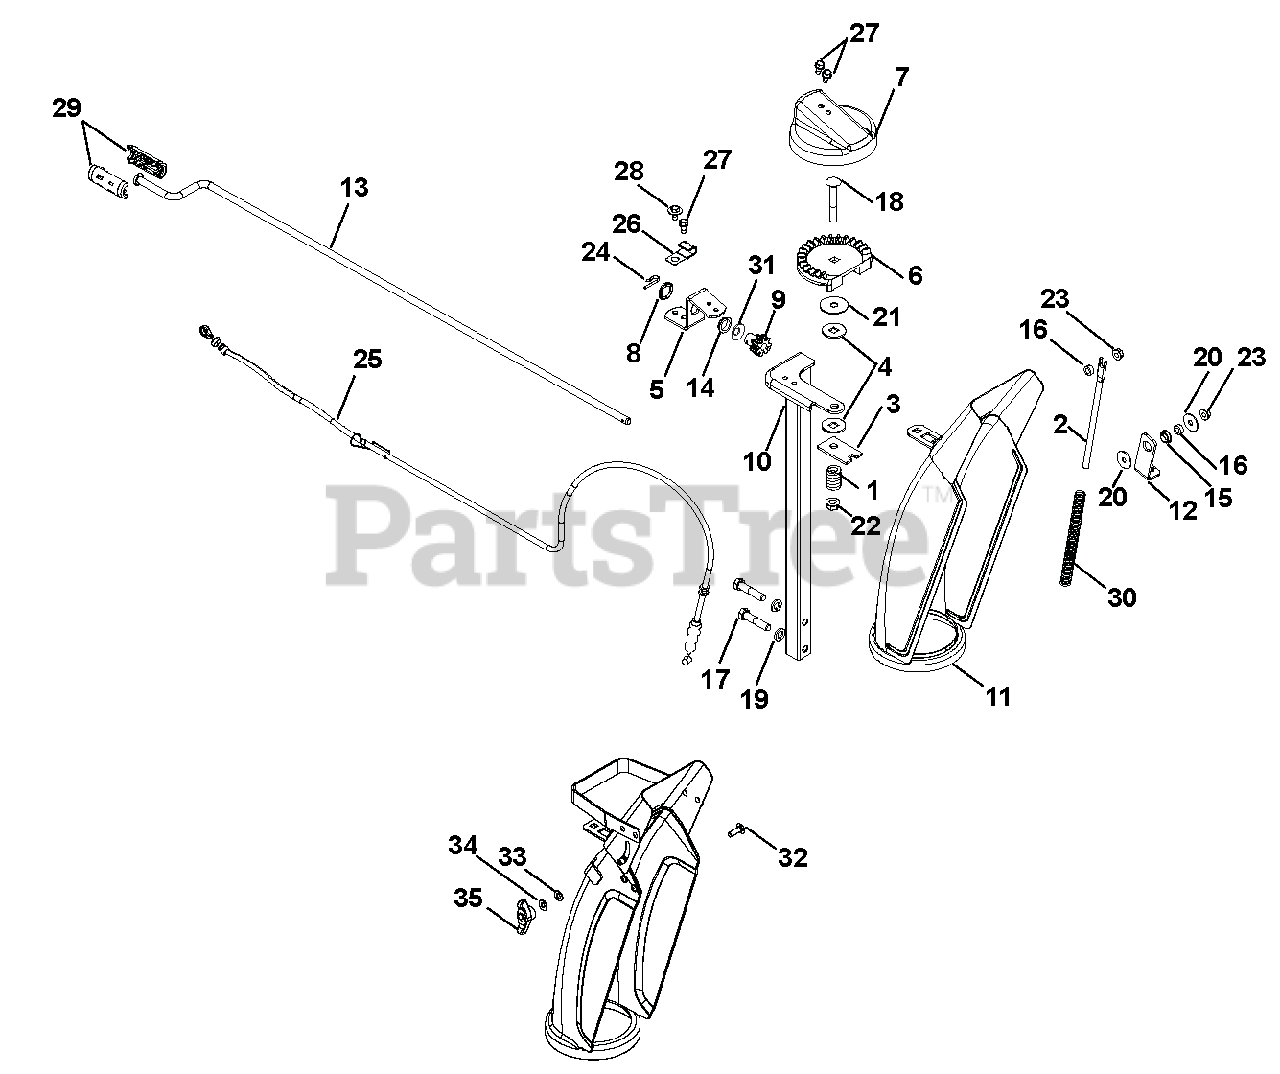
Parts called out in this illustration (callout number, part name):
1	SG-COMP .187X.56X1.62
2	ROD, DEFLECTOR CAP
3	PLATE, FRICTION
4	FRICTION WASHER
5	BRACKET, PINION GEAR
6	CHUTE GEAR
7	GEAR COVER
8	PUSHNUT .625
9	PINION GEAR W/BRACKET
10	CHUTE PEDESTAL, TALL COMPACT
11	CHUTE, DISCHARGE W/CAP & DECAL
12	BRACKET, CABLE ANCHOR
13	ROD, CHUTE CRANK, COMP&SNOTEK
14	BUSHING, POLYLINER-.63 SNAPIN
15	BUSHING, POLYLINER-.50 SNAPIN
16	BSHG-SLV .265X.500X.219
17	@BLT-HEX .38-16X1.75 GR5 YWZC
18	@BLT-RDHDSQNK .38-16X2.50 G5YZ
19	@WSHR-LK .38X.094 REG YWZC
20	WSHR-FL-STL .281X1.000X.063
21	@WSHR-FL-STL .406X1.25X.10 ZC
22	@NUT-LK-TOP-FLG .38-16 YWZC
23	@NUT-LK-TOP-FLG .25-20 YWZC
24	PIN, SPRING CLIP
25	CABLE, DEFLECTOR - COMPACT
26	J-CLAMP
27	SCR-TAP .25-20X.50 HWH TR YWZ
28	SCR-TAP .25-20X.50 LGHWH TR YZ
29	KNOB, CHUTE CRANK - SNAP BLK
30	SG-COMP .08X.40X6.50 14#/IN
31	WSHR-THRST .625 X 1.0 X .03
32	@BLT-RHDSSQNK .31-18X1.00 G5YZ
33	WSHR-FL-NY .375X.75X.060
34	@WSHR-FL-STL.344X.688X.065YWZC
35	KNOB,WING .31-18 UNC NYL/TALC
